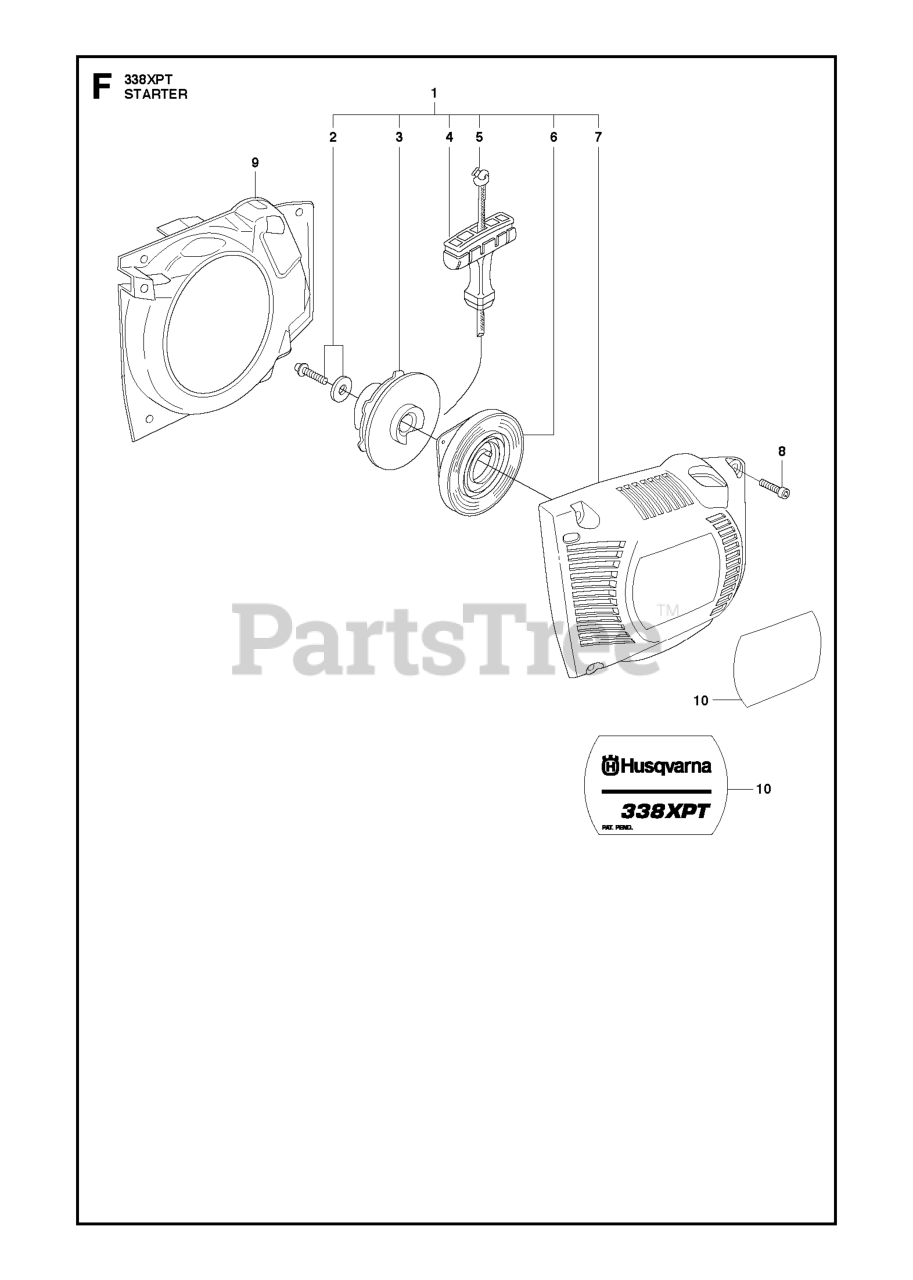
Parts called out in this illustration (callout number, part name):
1	STARTER ASSY
3	STARTER PULLEY
4	STARTER HANDLE
5	STARTER ROPE
6	RECOIL SPRING
7	STARTER HOUSING
9	AIR CONDUCTOR
10	DECAL 338 XPT
